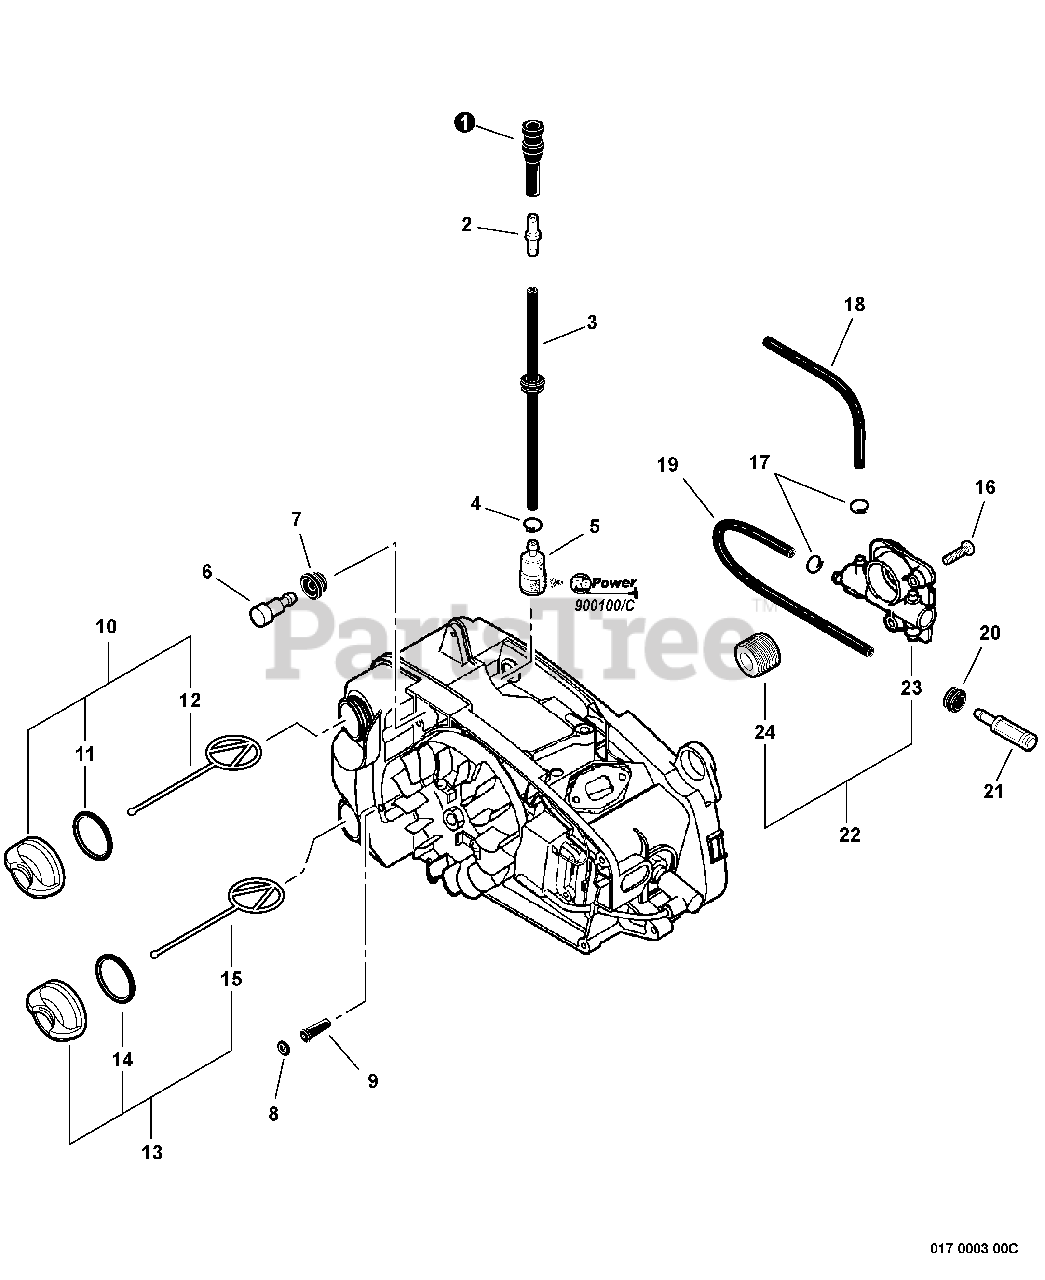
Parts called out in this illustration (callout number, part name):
1	PIPE - FUEL
2	CONNECTOR, PIPE
3	FUEL PIPE ASSY
4	CLIP - 6
5	FILTER, FUEL
6	VENT, FUEL TANK
7	GROMMET
8	O-RING - 4
9	VENT, TANK
10	CAP ASSY - ORANGE
11	O-RING - 18
12	CONNECTOR, CAP
13	CAP ASSY - BLACK
14	O-RING - 18
15	CONNECTOR, CAP
16	SCREW - 4X12
17	CLIP - 6.5
18	PIPE - 3X6X90 -- BLACK
19	PIPE - 3X5X195 -- BLACK
20	GROMMET
21	FILTER, OIL
22	AUTO-OILER ASSY
23	AUTO-OILER ASSY
24	GEAR - WORM
25	RePower TUNE-UP KIT
